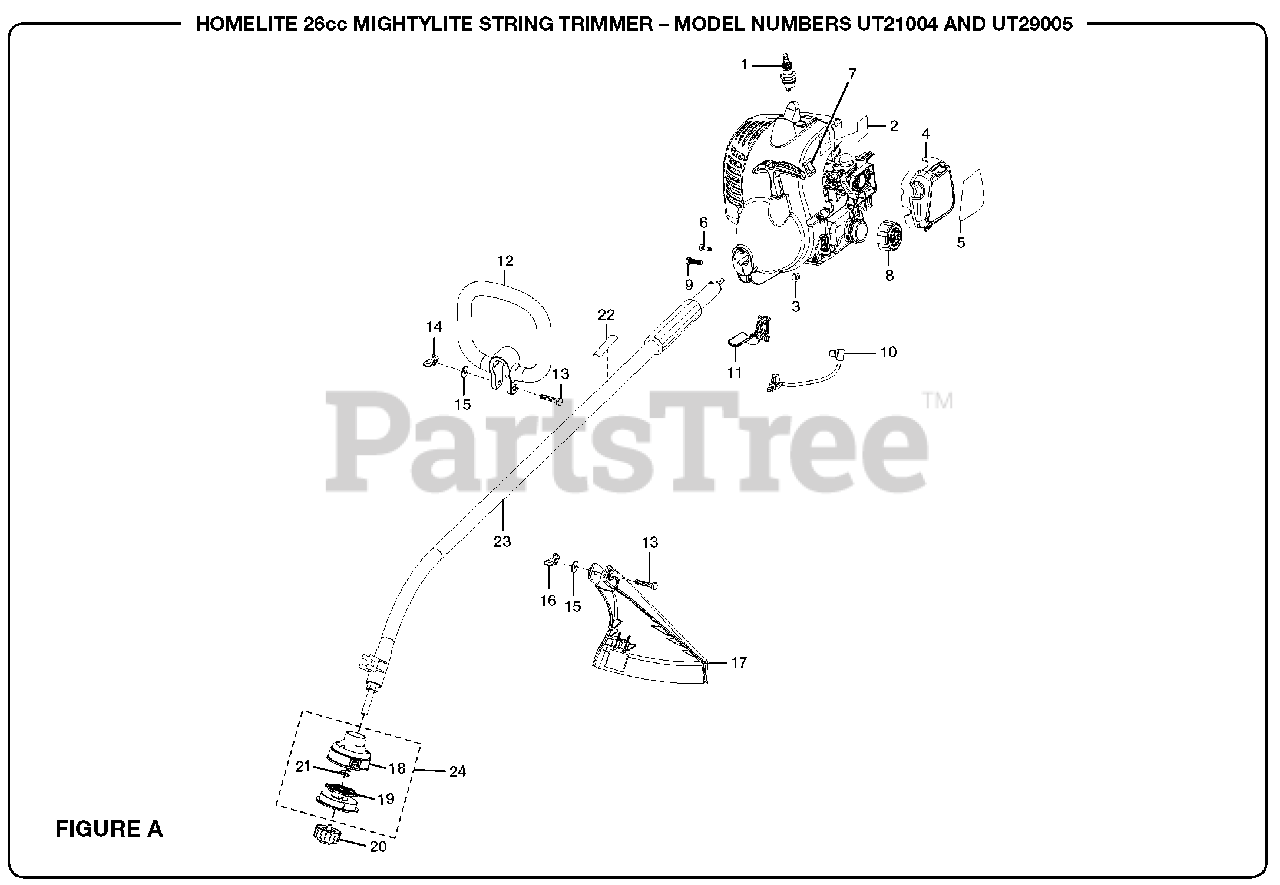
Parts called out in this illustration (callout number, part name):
1	Spark Plug (Champion RCJ6Y)
2	Logo Label
3	Hex Nut (M6)
4	Air Box Cover
5	Starting Label
6	Screw (8-16 x 5/16 in.)
7	Switch
9	Bolt (M6 x 20 mm)
10	Throttle Cable
11	Throttle Trigger
13	Bolt (1/4-20 x 40 mm)
14	Wing Nut (1/4-20)
15	Washer (1/4-20)
16	Wing Nut (1/4-20)
17	Curved Shaft Grass Deflector
18	Dual String Head Housing
19	Dual Line Spool and String
20	Spool Retainer
21	Spring
22	Warning Label
23	Boom Assembly
24	String Head Assembly
